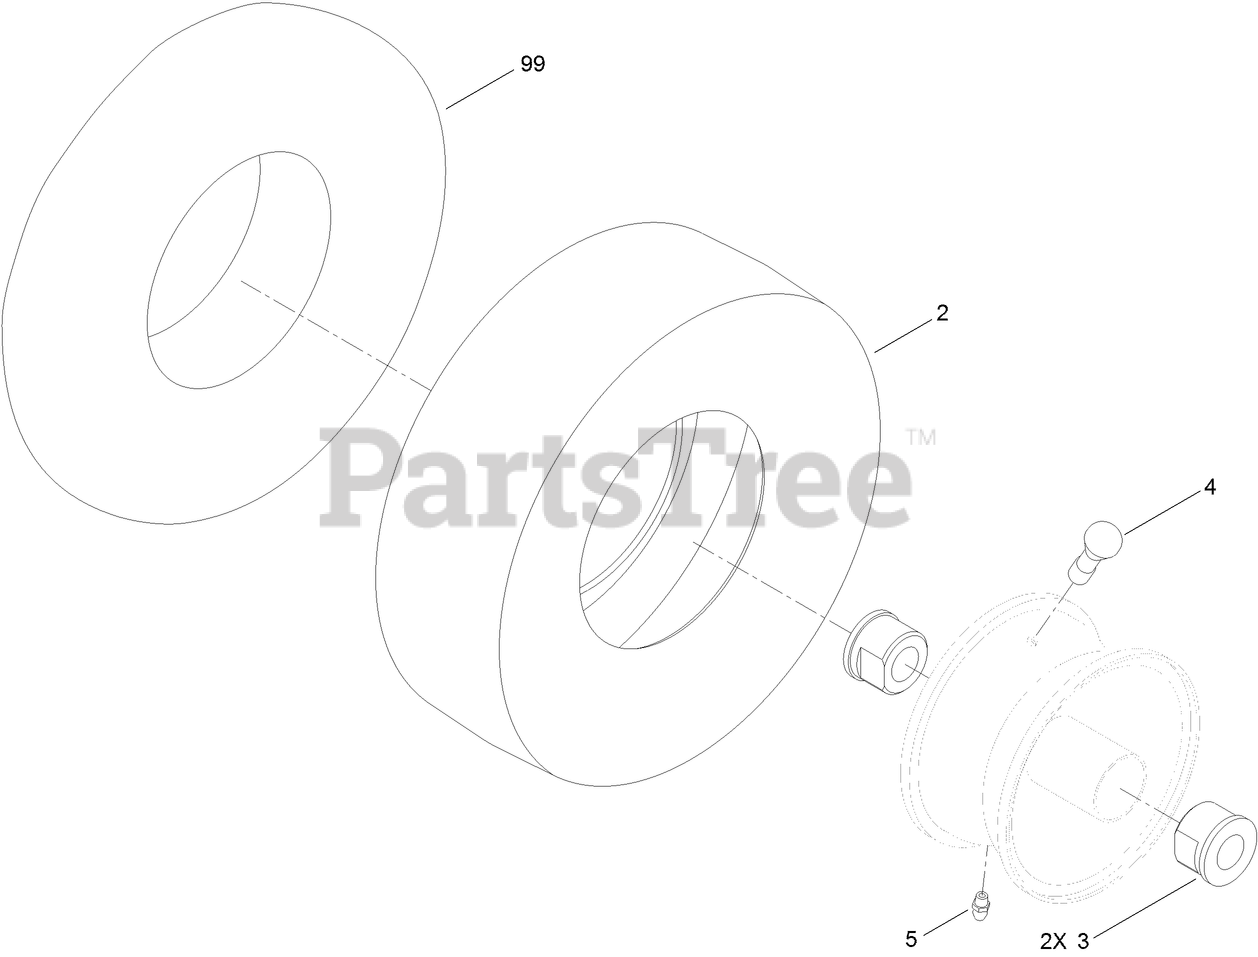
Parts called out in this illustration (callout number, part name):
2	TIRE-SMOOTH
3	BUSHING-FLANGE
5	FITTING-GREASE
99	TUBE-INNER
